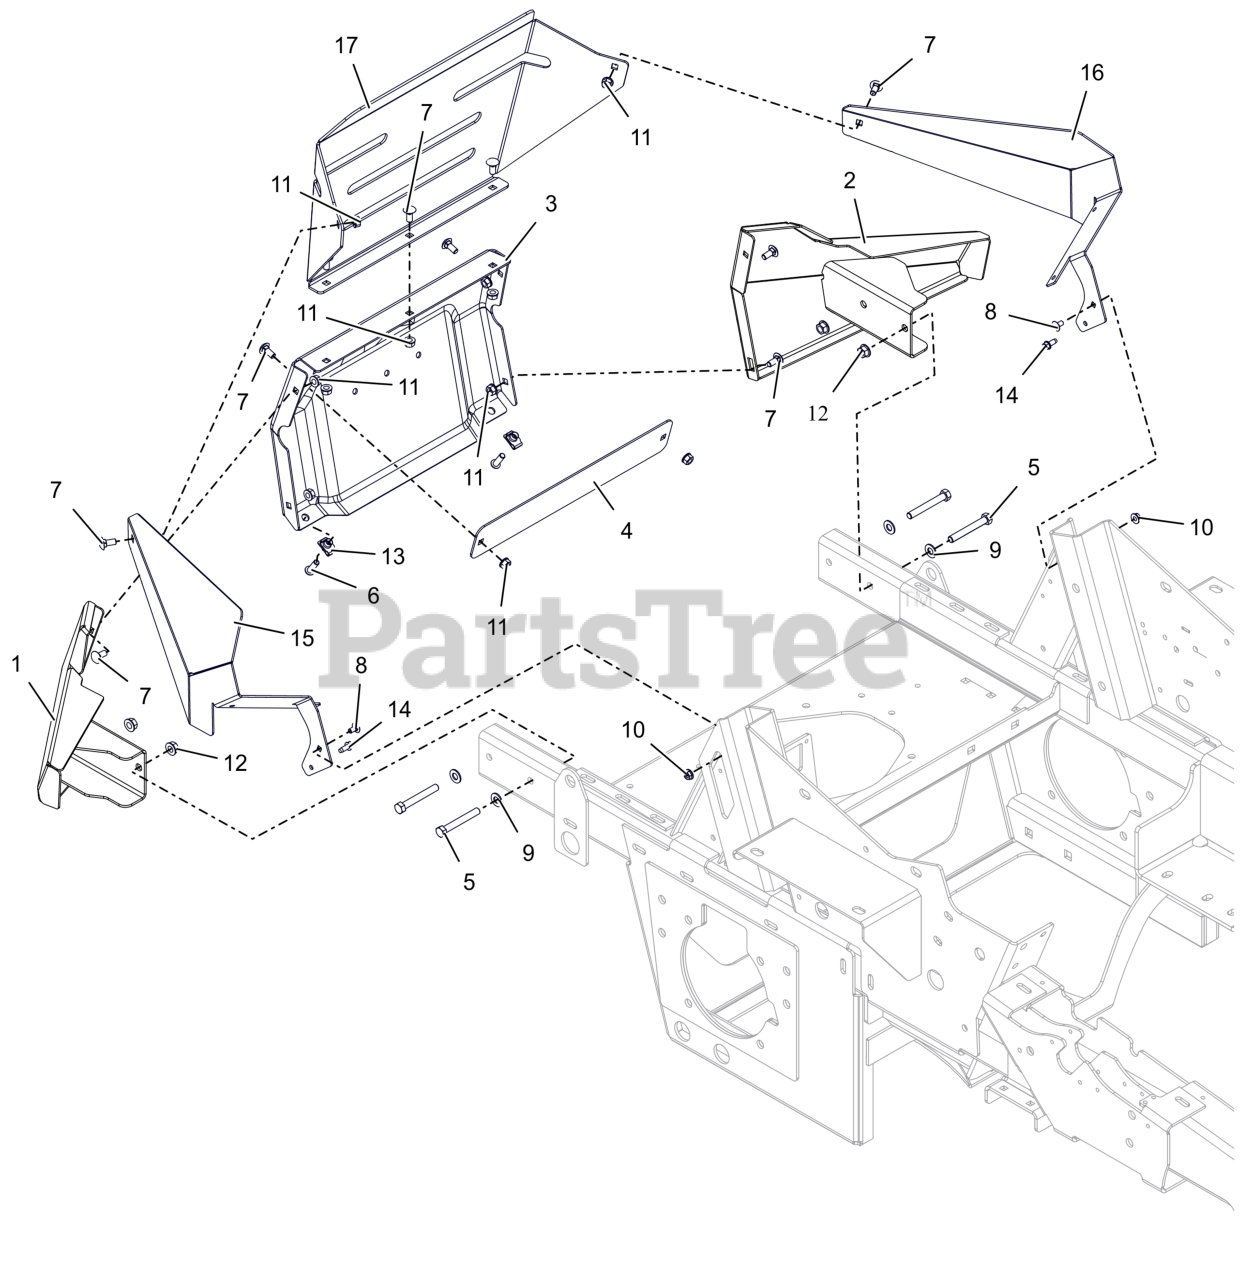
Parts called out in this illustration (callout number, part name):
1	WLDMT, RIGHT REAR BUMPER WING (RED) W/ SAFETY DECALS
2	WLDMT, LEFT REAR BUMPER WING (RED) W/ SAFETY DECALS
3	BUMPER, COMMERCIAL REAR
4	PLATE, BACKER (BLACK)
5	BLT, HEX .38-16X2.75 G5 ZCC
6	BLT,SHCS-BTN .31-18X1.00 ZCC
7	BLT,RHSN .31-18X.75 G5 ZCC
8	BLT, RHSSN.25-20X.500 G5 ZCC
9	WSHR,FLT .406X.812X.065 ZCC
10	NUT-LK-CTR-FLG .25-20 ZC120
11	NUT,LK-CTR-FLG .31-18 GF ZCC
12	NUT-LK-CTR-FLG .375-16 GF ZCC
13	NUT-CLIP RETAINER 5/16-18X.56
14	SCR,TAP .25-20X.625 HWH ZCC
15	BRKT- RH SIDE WRAP MTG
16	BRKT- LH SIDE WRAP MTG
17	WRAP- REAR CENTER
